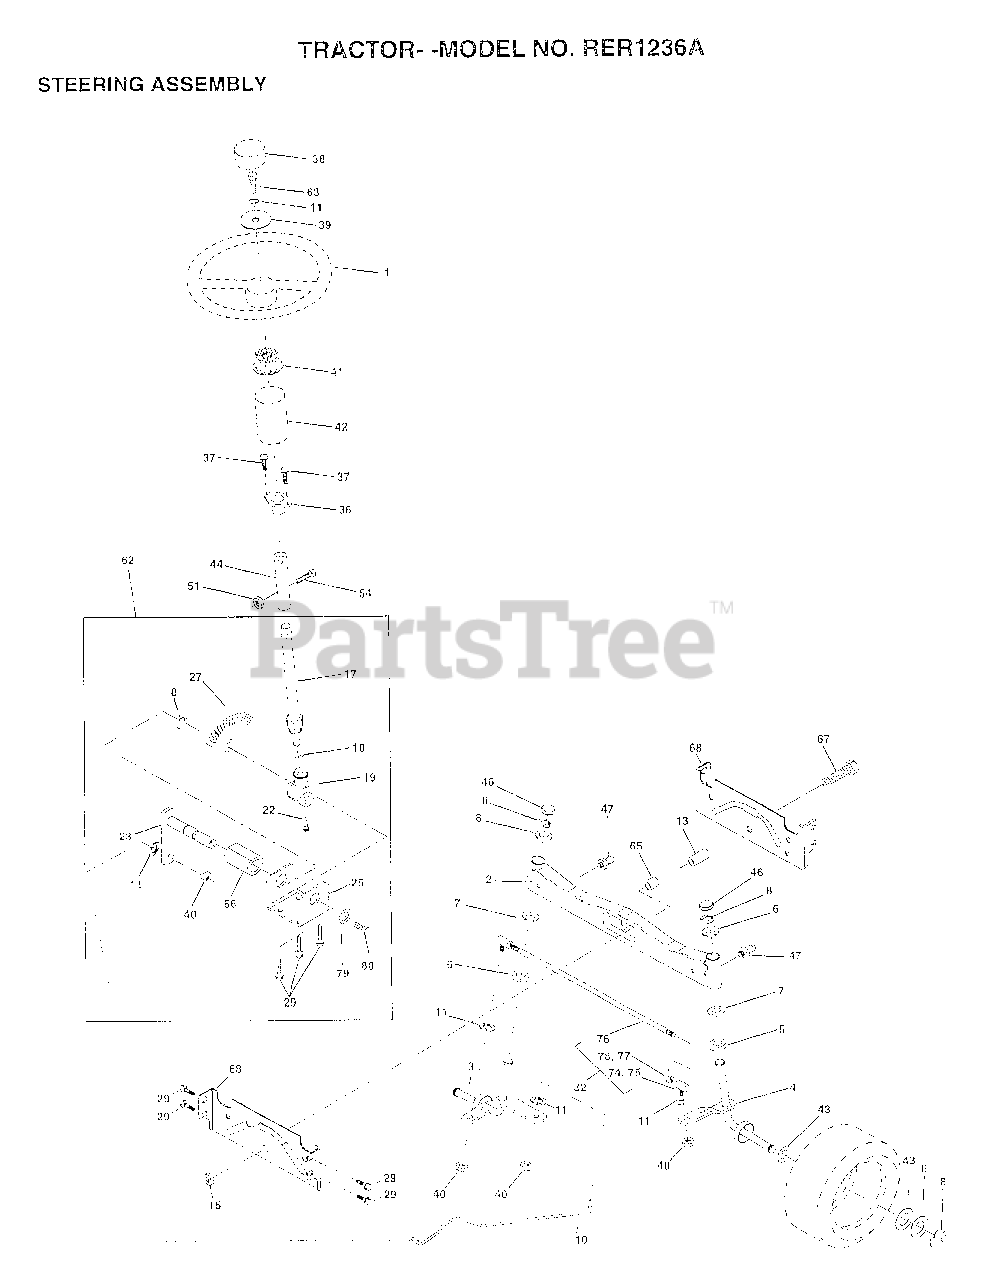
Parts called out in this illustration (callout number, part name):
3	"SPINDLE ASM,LH"
4	"SPINDLE ASM,RH"
5	WASHER .T
6	WASHER
7	WASHER
8	RING
10	LINK.DRAG
11	LOCKWASHER
13	BEARING.FRT.SPACER.AXLE
15	"NUT-LOC,FLANGE LT"
17	SHAFT ASM STEERIN
18	WASHER THRUST
19	SUPPORT.SHAFT.STEER
22	SCREW.HX.WSH.HD
23	SHAFT.ASM.PITMAN
25	BRKT-STEERING
27	GEAR SECTOR
29	SCREW
32	ROD.ASM.TIE.BALL
36	BUSHING.STEERING
37	"SCREW-TT,10-32 FL"
38	ST WHL INSERT CAP
39	WASHER T
40	GRIPCO NUT
41	ADAPTER LT
42	BOOT.STEER.PL
43	WASHER
44	EXT SHAFT STEERIN
46	CAP
47	ZERK M
51	NUT
54	BOLT
62	KIT.STEER.ASM
63	BOLT
65	SPACER AXLE
66	"BEARING-ARM,PITMA"
67	BOLT
68	BRACE AXLE
74	JOINT.RH
75	JOINT.LH
77	NUT
78	NUT
79	WASHER
80	BOLT.HX.NYLON3/8-16X3/
